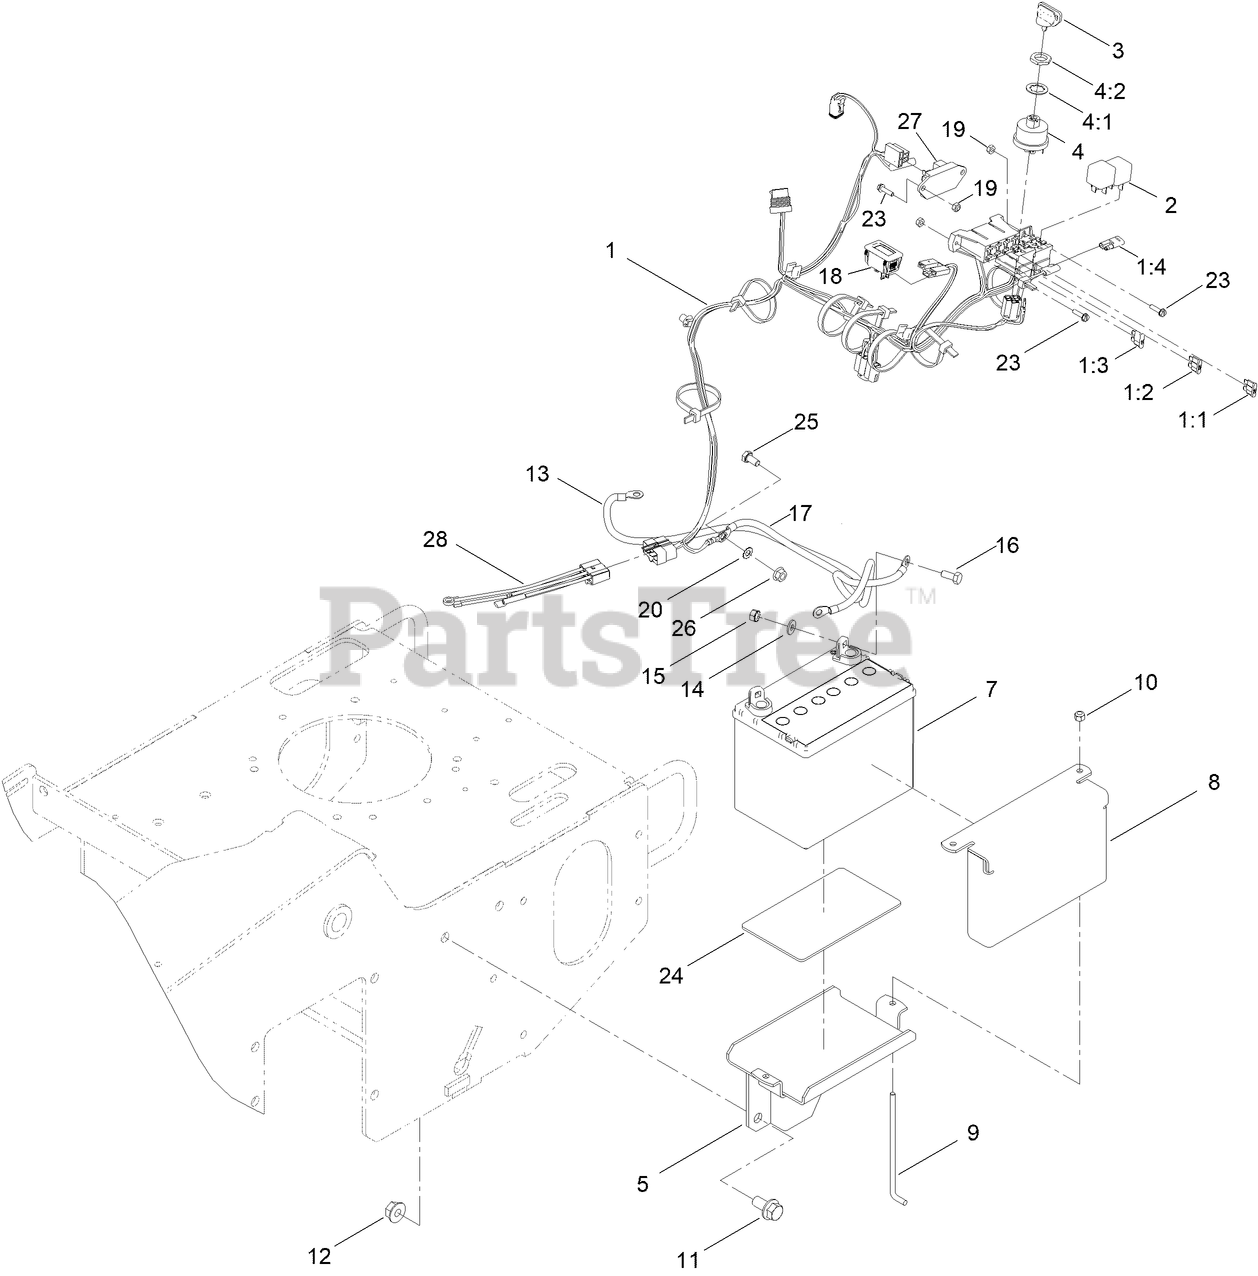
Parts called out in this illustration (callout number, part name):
1	HARNESS-WIRE
1:1	FUSE-BLADE, 30 AMP
1:2	FUSE-BLADE, 25 AMP
1:3	FUSE-BLADE, 20 AMP
1:4	CAP-PLUG
2	RELAY
3	KEY-IGNITION
4:1	WASHER-LOCK
4:2	NUT-HH
5	TRAY-BATTERY
8	PLATE-HOLD DOWN, BATTERY
9	HOLDOWN-BATTERY
10	NUT-LOCK, NI
11	SCREW-HHF
12	NUT-HHF
13	CABLE-BATTERY, POSITIVE
14	WASHER-FLAT
15	NUT-KEPS
16	SCREW-HH
17	CABLE-BATTERY, BLACK
18	HOURMETER
19	NUT-LOCK, NI
20	WASHER-LOCK
23	SCREW-HWH
24	PAD-SKID, ANTI
25	SCREW-HH
26	NUT-HF
27	MODULE-DELAY
28	HARNESS
